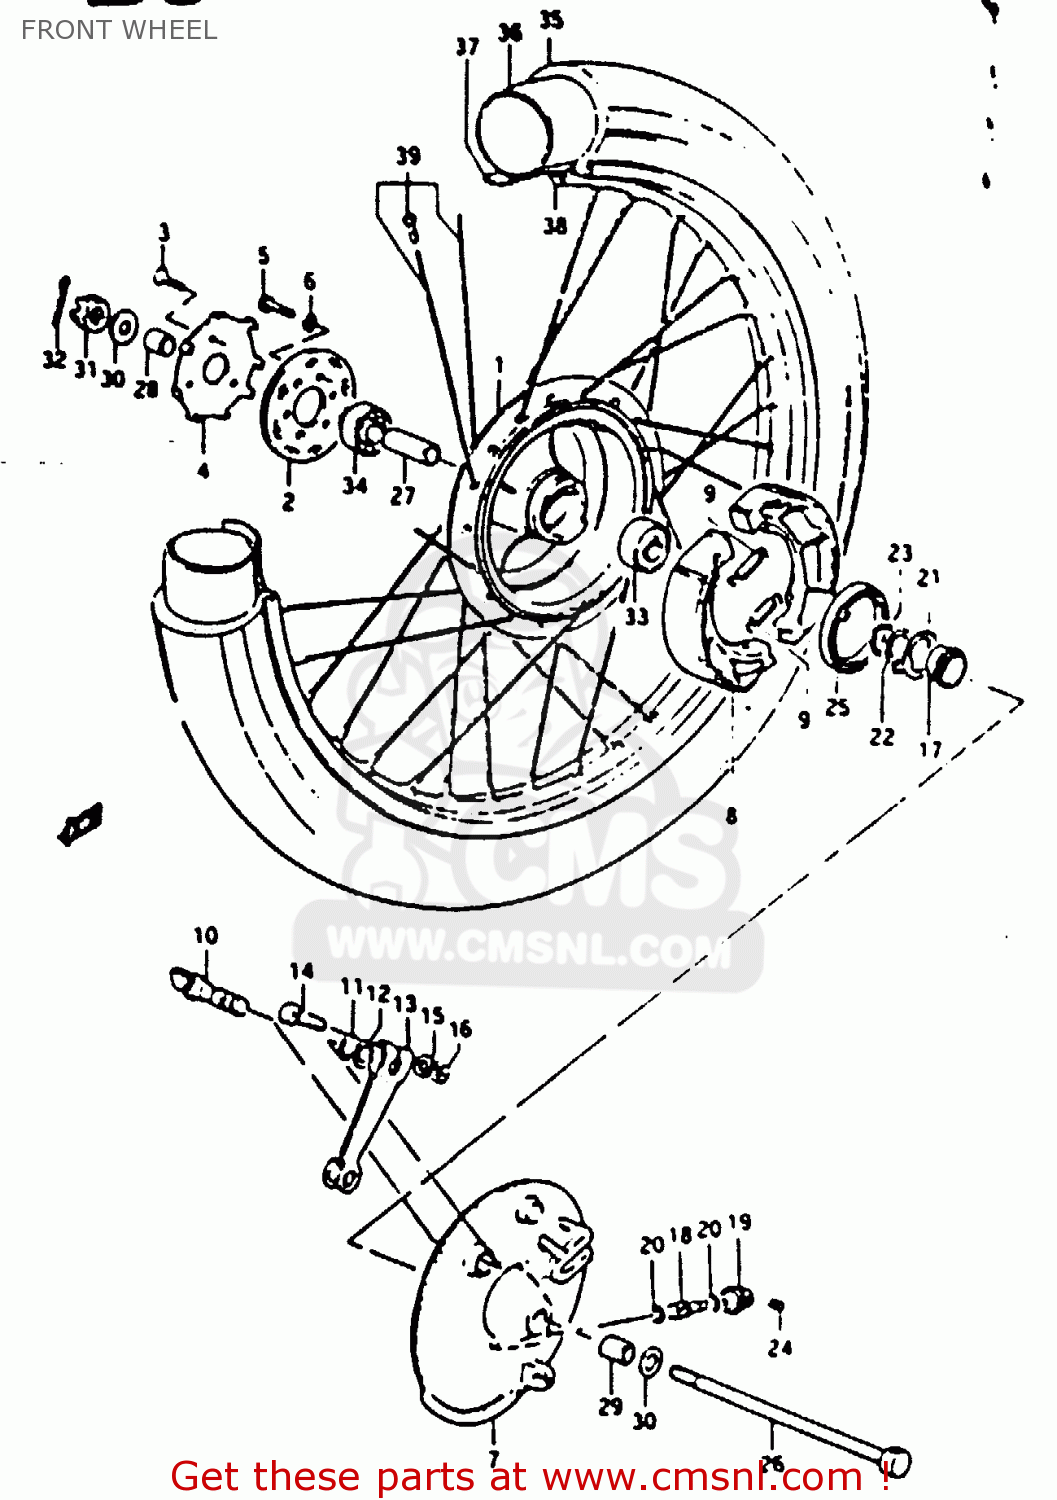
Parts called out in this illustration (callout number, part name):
1	HUB,FR WHEEL
2	FLANGE,FR HUB,R
3	SCREW
4	RETAINER,FR HUB BEARING,R
5	BOLT, UPPER
6	LOCK WASHER
7	PANEL,FRONT HUB
8	SHOE,BRAKE
9	SPRING(L:34)
10	CAM,FRONT BRAKE
11	O-RING (D:2.4 ID:13.8)
12	WASHER (14.5X22X1.6)
13	LEVER,FR BRAKE CAM
14	BOLT(6X33)
15	WASHER
16	NUT
17	GEAR,SPEEDOMETER
18	PINION,SPEEDOMETER
19	BUSH,METER GEAR OUTER
20	WASHER (5.1X9X0.4)
21	DRIVER,SPEEDOMETER GEAR
22	WASHER(18.5X24X1)
23	CIRCLIP
24	SCREW
25	OIL SEAL (43X58X7)
26	AXLE,REAR
27	SPACER (12.6X19X52)
28	SPACER (12.2X19X18.5)
29	SPACER(12X20X34.5)
30	WASHER
31	NUT 12MM
32	COTTER PIN
33	BEARING
34	BEARING, RH
35	TIRE,FRONT
36	TUBE
37	PROTECTOR,WHEEL,INNER
38	RIM,FR WHEEL(1.60X21)
39	SPOKE SET,FRONT
